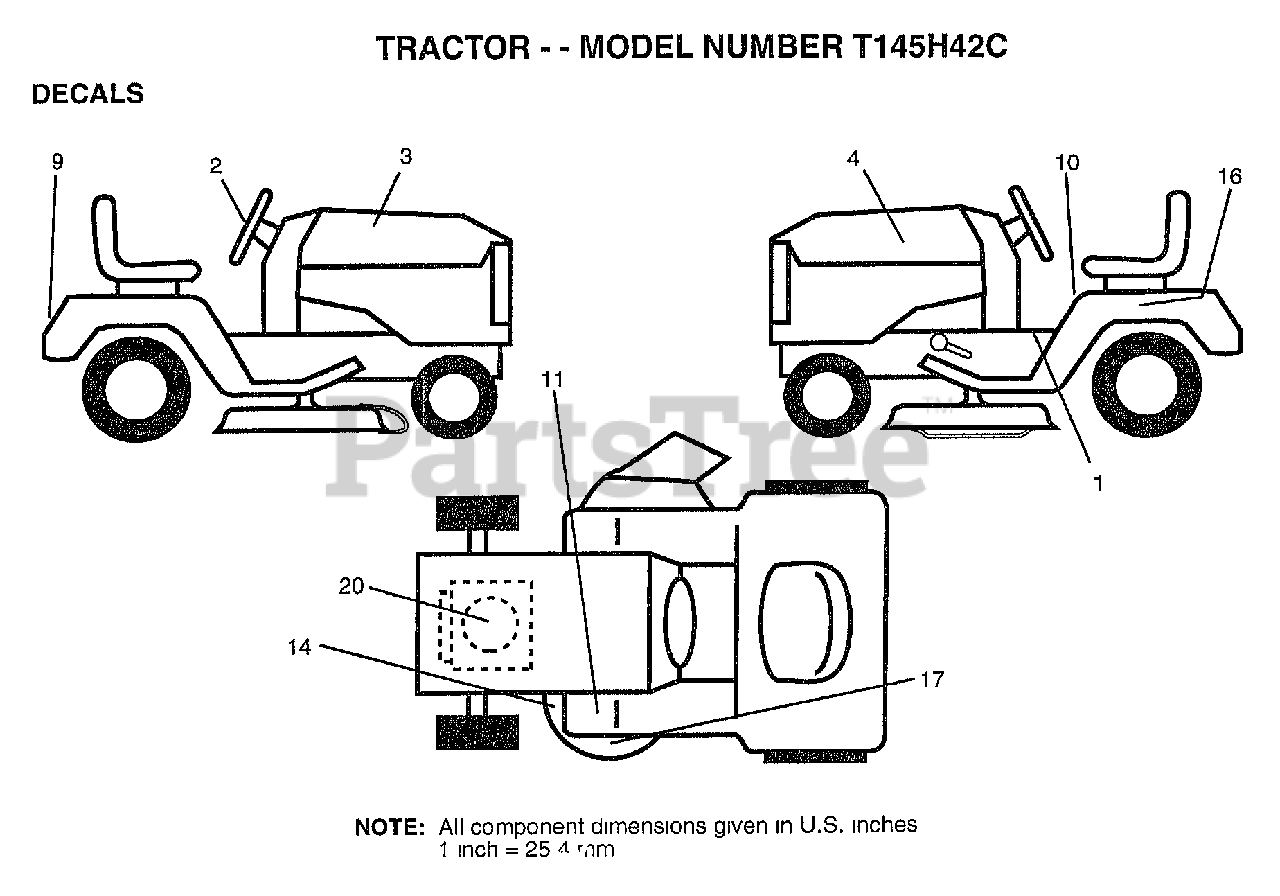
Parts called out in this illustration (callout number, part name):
1	"DECAL INST,SADDLE"
2	"DECAL,STR WHL T"
3	DECAL.HOOD.RH.CO.
4	DECAL.HOOD.LH.CO.
9	DECAL.FEND.HYD.CP
10	"DECAL DANGER,FEND"
14	"DECAL-SCHEM,BELT"
16	DECAL.BATRY.3-3908
20	DECAL, ENGINE
